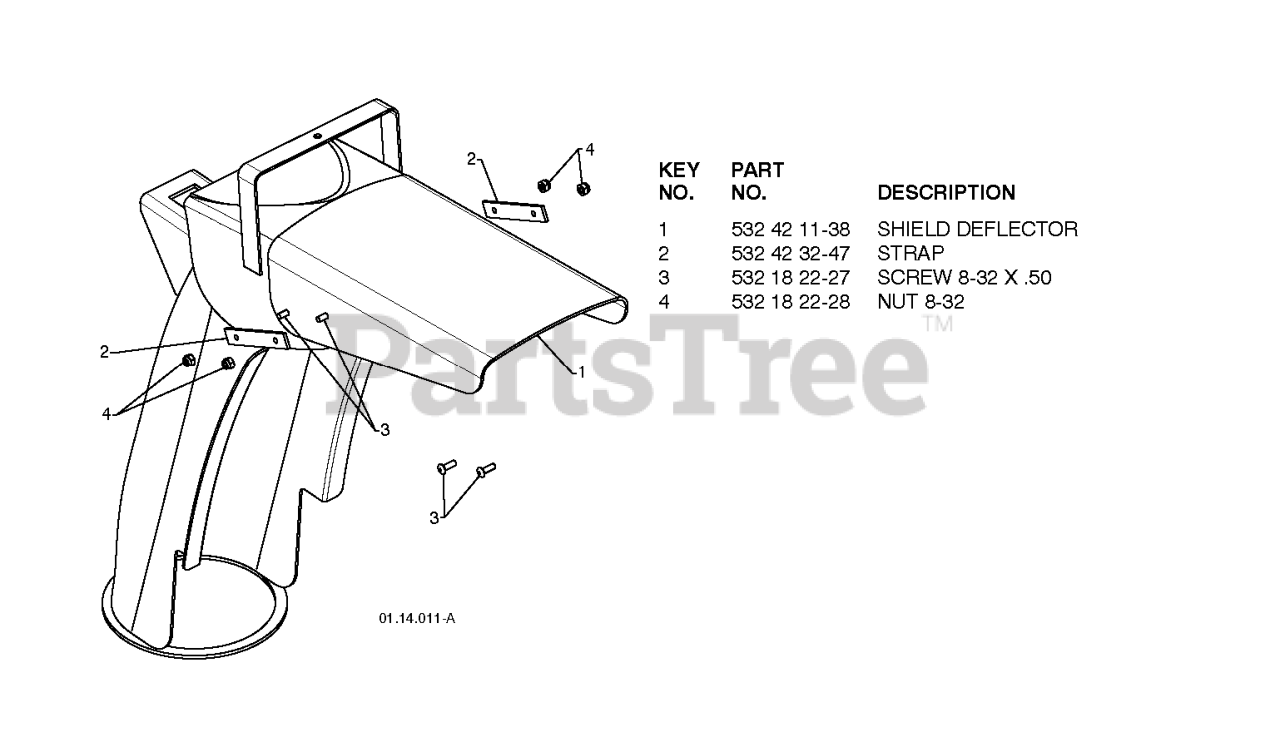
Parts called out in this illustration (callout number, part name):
1	SHIELD.DEFLECTOR.BLACK.SNOW
2	DEFLECTOR SHIELD STRAP
3	SCREW.#8.MACH
4	NUT.HEX.#8
